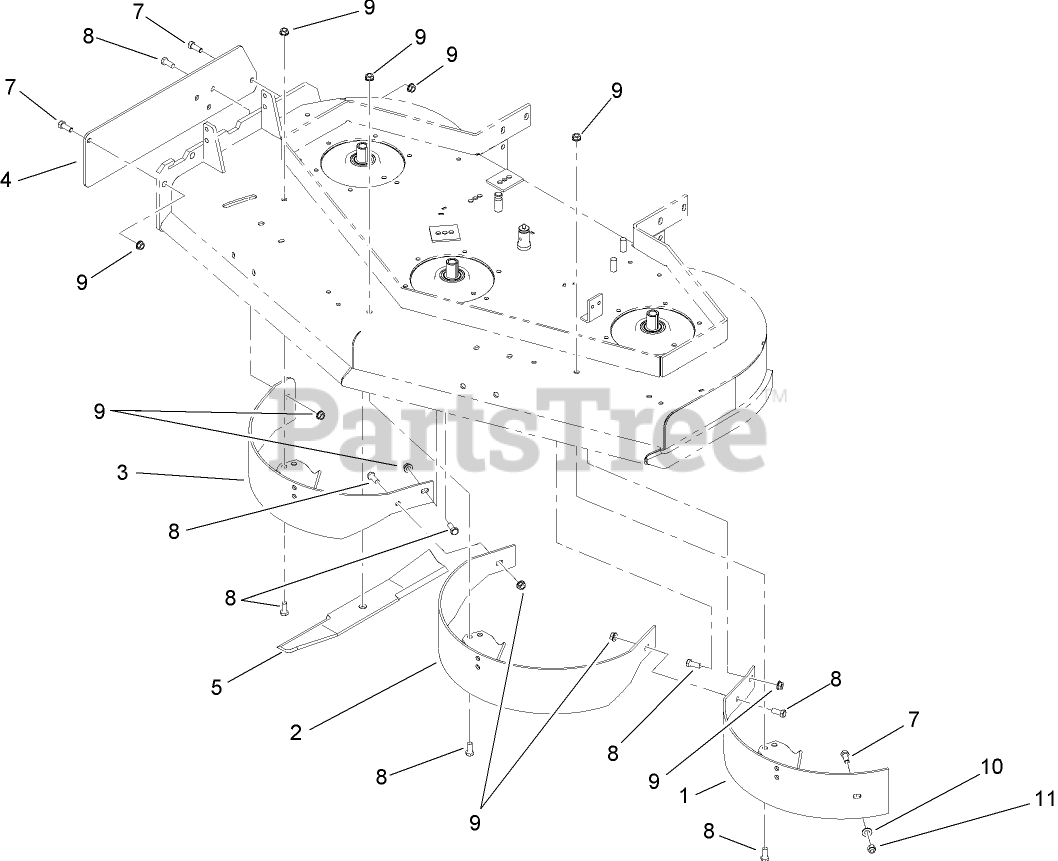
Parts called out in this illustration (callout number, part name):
1	LH BAFFLE ASM
2	CENTER BAFFLE ASM
3	RH BAFFLE ASM
4	PLATE-DISCHARGE
5	BLADE-RECYCLER
7	SCREW-HH
8	SCREW-HH
9	NUT-HHF, WHIZ
10	WASHER-FLAT
11	NUT-LOCK, NI
